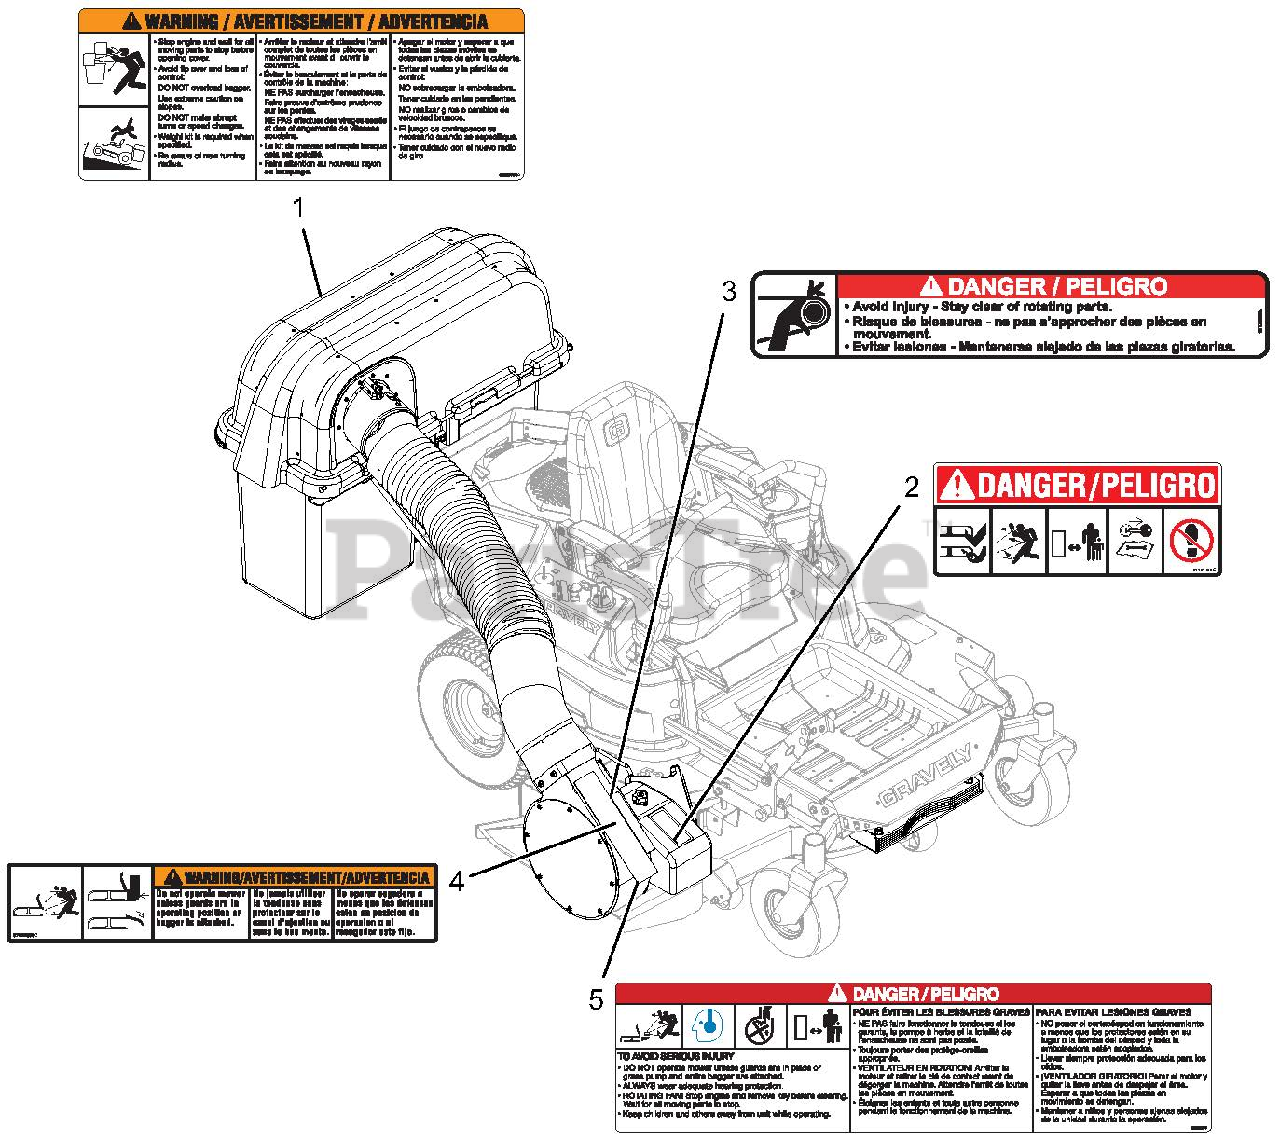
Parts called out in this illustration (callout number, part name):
1	DECAL, BAGGER COVER
2	DECAL, MOWER PAN DANGER
3	DECAL- DANGER
4	DECAL-CAUTION, GRASS PUMP
5	DECAL, WARNING
